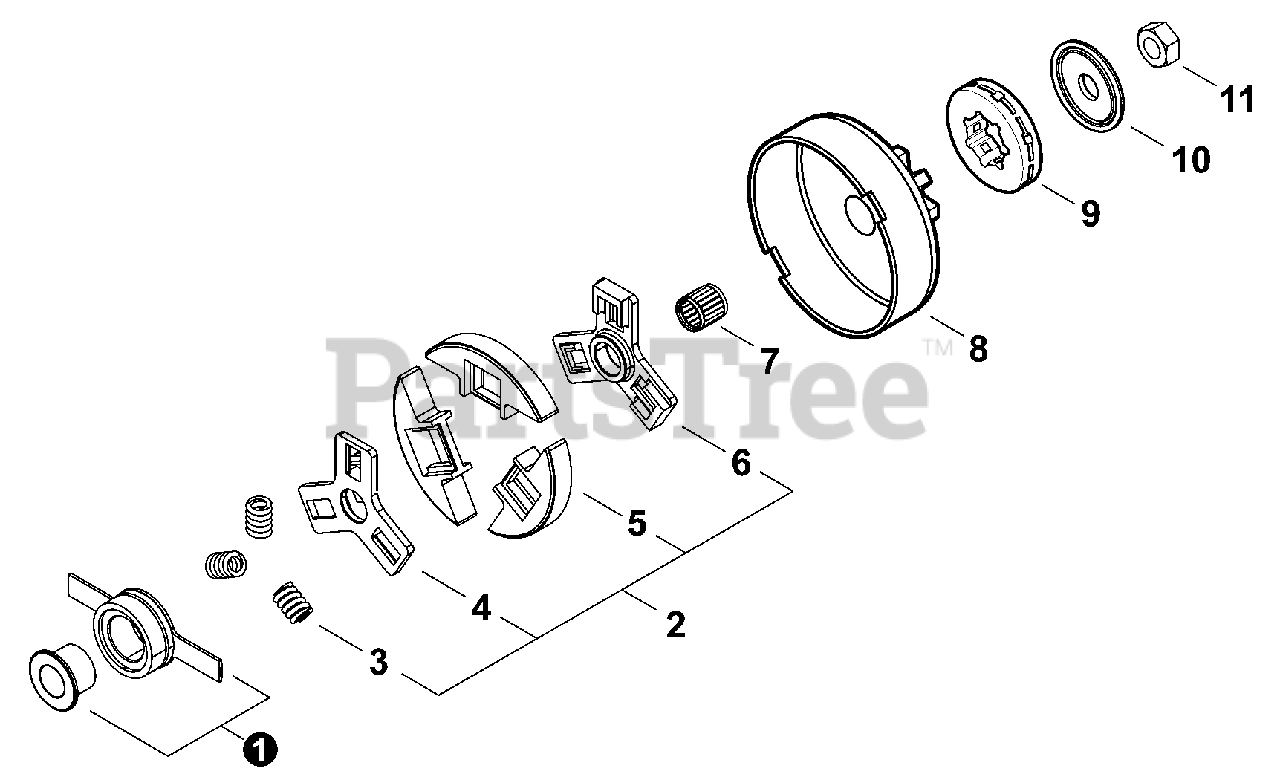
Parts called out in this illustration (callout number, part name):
1	GEAR ASSY, WORM
2	CLUTCH ASSY
3	SPRING, CLUTCH
4	BOSS, CLUTCH A
5	Clutch Shoe
6	BOSS, CLUTCH B
7	BEARING, NEEDLE 10
8	DRUM, CLUTCH
9	SPROCKET, 0.325 RIM
10	WASHER 10
